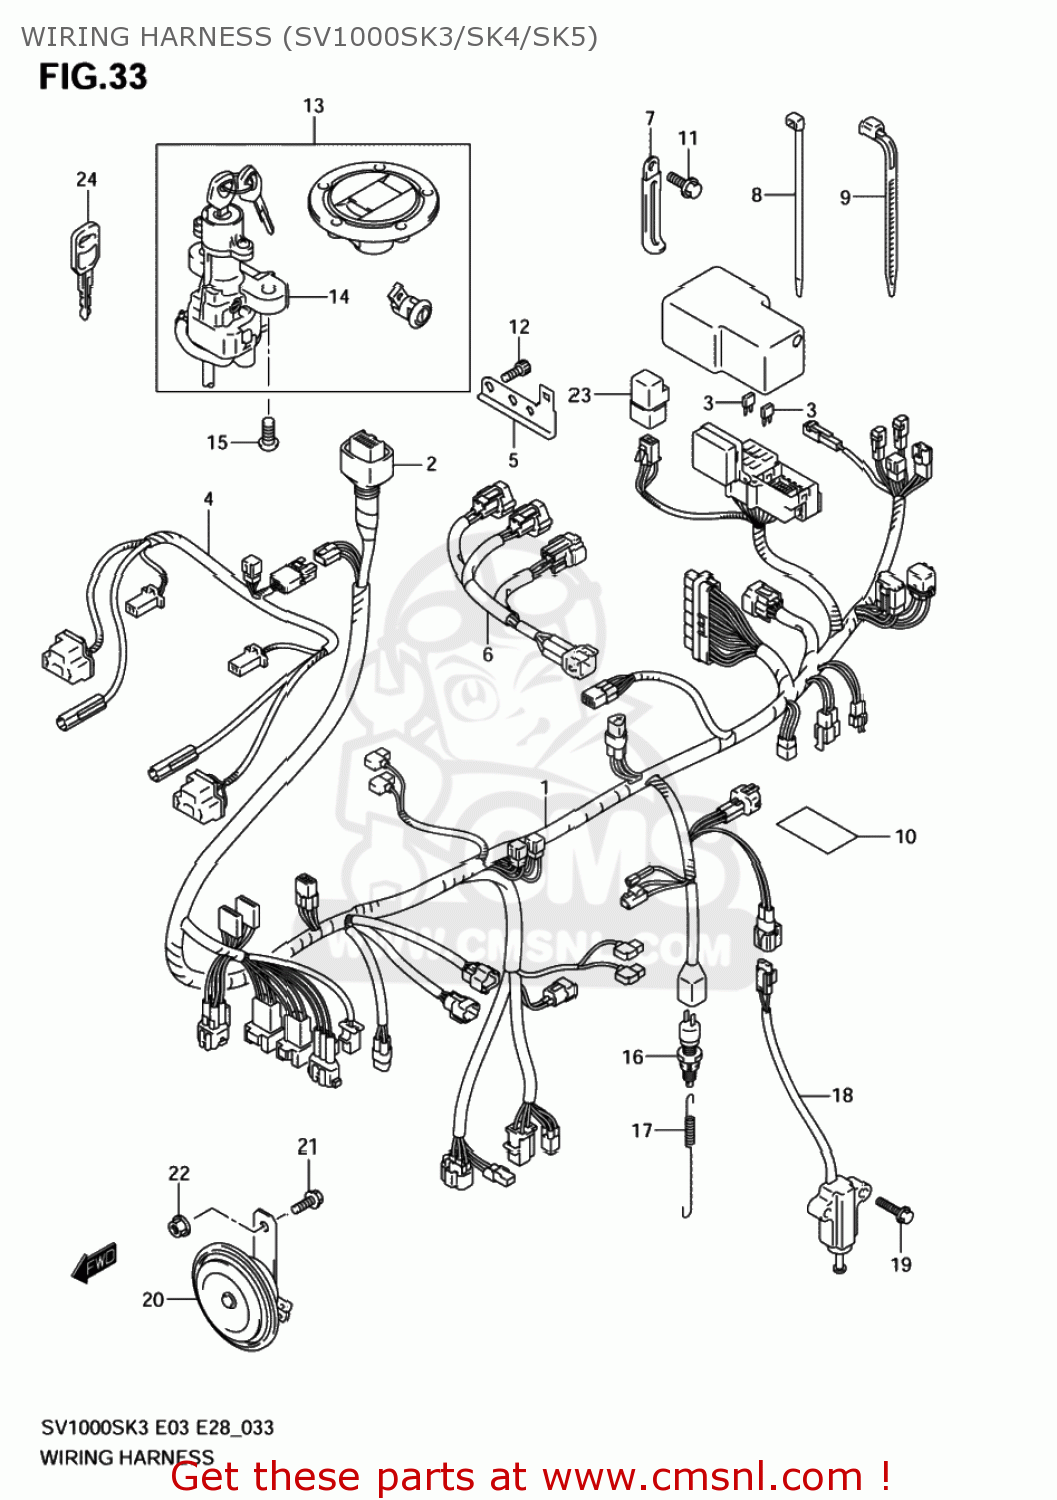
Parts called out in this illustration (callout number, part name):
1	HARNESS,WIRING NO.1
2	COVER,SPEEDOMETER COUPLER
3	FUSE(10A)
4	HARNESS,WIRING NO.2
5	HOLDER,COUPLER
6	WIRE,INJECTOR LEAD
7	CLAMP(L:45)
8	CLAMP(L:145)
9	CLAMP(L:95)
10	TAPE,WIRING HARNESS(28X50X0.13
11	BOLT
12	BOLT,VAC.PIPE
13	LOCK SET
14	LOCK ASSY,STEE
15	BOLT(8X20)
16	SWITCH ASSY,STOP LAMP
17	SPRING
18	SWITCH ASSY,SIDE STAND
19	BOLT
20	HORN ASSY
21	BOLT
22	NUT
23	RELAY ASSY
24	KEY,BLANK
